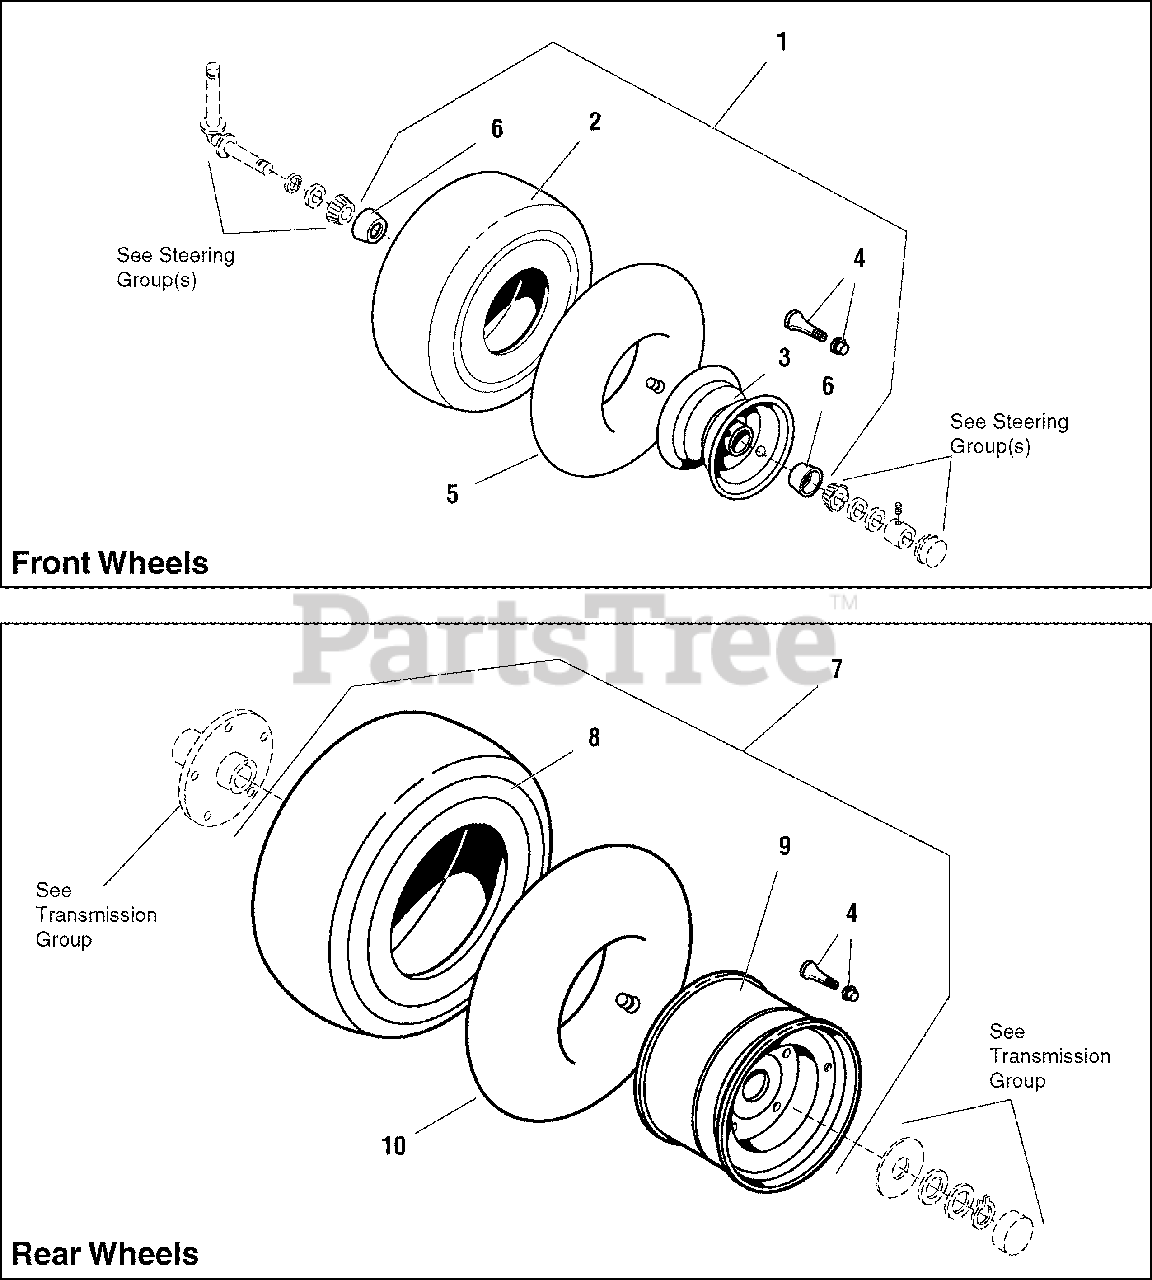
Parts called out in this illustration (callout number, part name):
1	FRONT WHEEL & TIRE ASSEMBLY, Metallic Gray,16 x 6.50-8 (Includes Ref. Nos. 2, 3, 4, & 6)
2	TIRE, Front, 16 x 6.50 - 8, Multi-Trac
3	WHEEL, Front (Includes 2 of Ref. No. 6)
4	VALVE STEM
5	TUBE, (Not Standard), Front
6	BEARING CUP, Front
7	REAR WHEEL & TIRE ASSEMBLY, Metallic Gray, 23 x 10.50-12 (Includes Ref. Nos. 4, 8 & 9)
8	TIRE, Rear, 23 x 10.50 - 12, Multi-Trac
9	WHEEL, Rear
10	TUBE, (Not Standard), Rear
